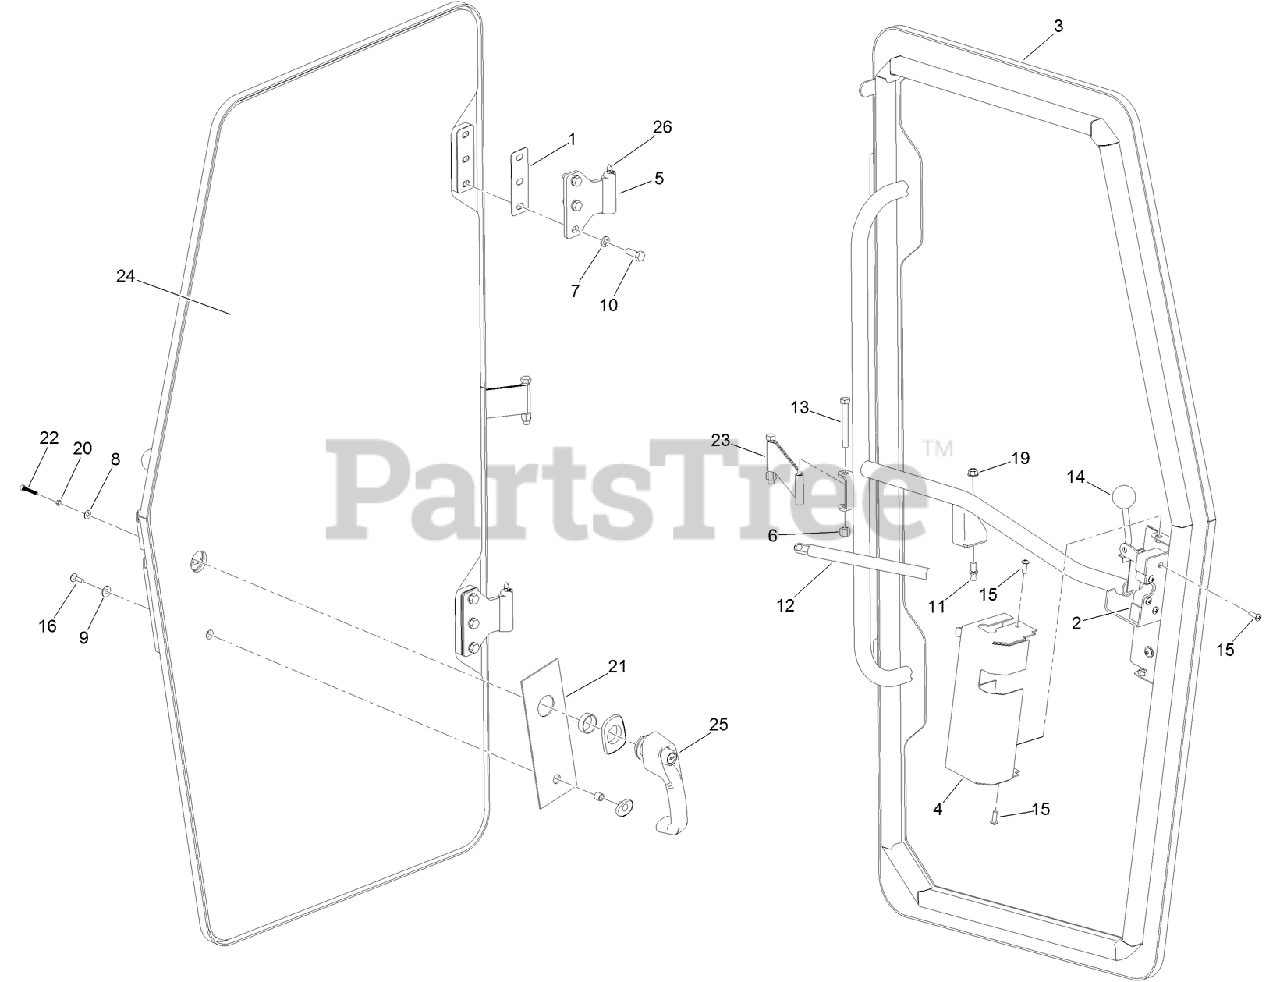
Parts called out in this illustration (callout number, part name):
1	SHIM-HINGE, DOOR
3	DOOR-LH
4	COVER-LATCH, LH
5	HINGE-DOOR, LH
7	WASHER-LOCK
8	WASHER-FLAT
9	WASHER-FLAT
10	BOLT-HHCS
11	STUD-BALL, GAS SPRING
12	SPRING-GAS
13	BOLT-HHCS
19	NUT-HEX
20	NUT-M5
21	GASKET-HANDLE, DOOR
22	BOLT-SHCS
23	STRAP-HOLDER, DOOR
24	GLASS-DOOR, LH
25	HANDLE-EXTERIOR
26	CAP-GREASE, ZERK
